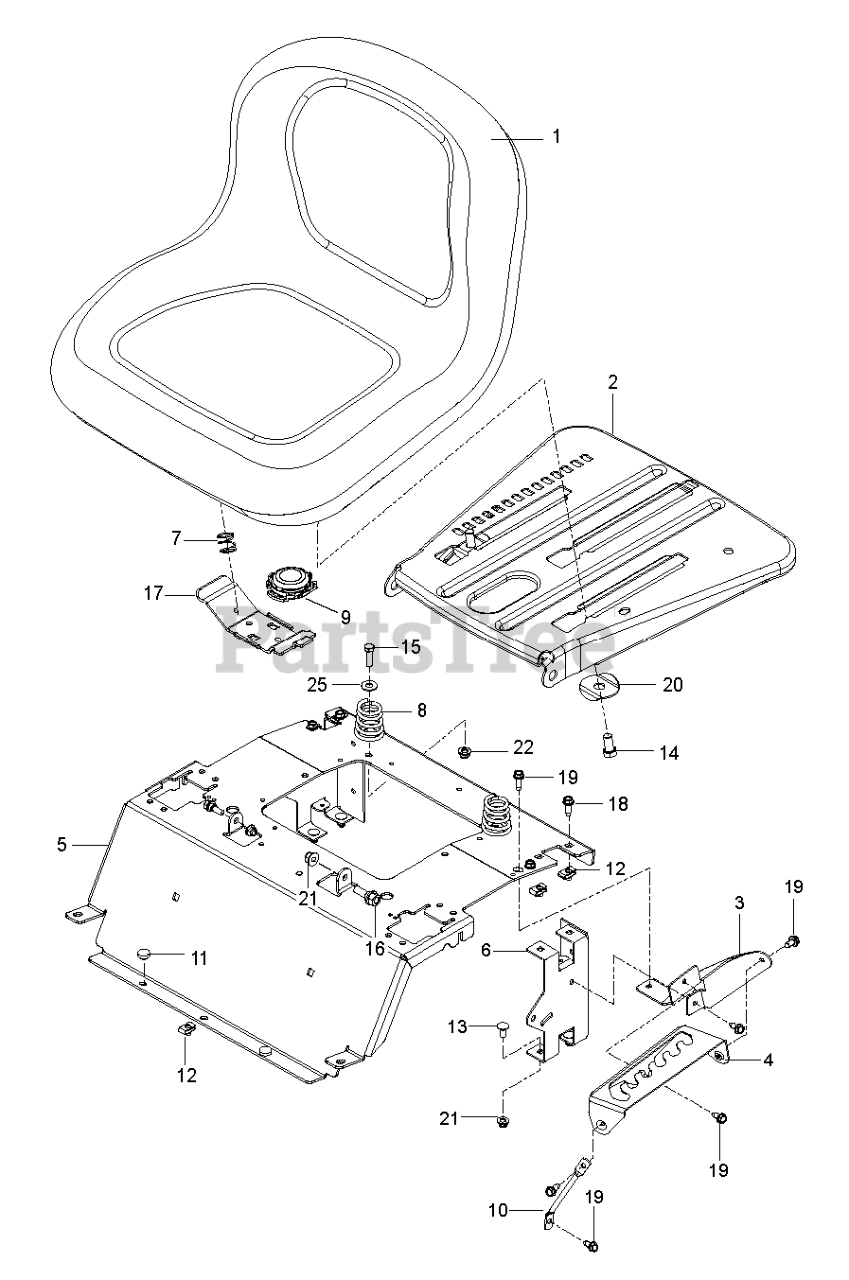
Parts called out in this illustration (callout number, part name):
1	SEAT.TH150.MS498.GRY.HUSQ.TEX
2	PLATE.PNT.SEAT.SLIDE.3PT.EDIP
3	PLATE.SUPPORT.DECK.LIFT.X431
4	PLATE.DECK.LIFT.X431
5	PLATE SEAT SUPPORT; RZ ORANGE
5	SUPPORT.SEAT.RZ.HUSQ.ORANGE
6	SUPPORT REAR SEAT BLACK
7	SPRING.LATCH.SEAT.TEX
8	SPRING.COMPRESS.SEAT.TAPERED
9	SWITCH.SEAT.DELTA.OPC.
10	SUPPORT.LEG.DECK.LIFT
11	GROMMET.BUMPER
12	U-CLIP 5/16-18 NUT RETAINER
13	BOLT 5/16C X 3/4" CARRIAGE
14	BOLT
14	RHSNB 5/16-18 X 2-1/2 GR5 ZD
15	BOLT
16	BOLT, SHOULDER
17	HANDLE.SLIDE.SEAT.TEX.BLACK
18	SCREW.THDROL.5/16-18X3/4.TTY
19	BOLT.5/16HEX.WHS.HD
20	WASHER.WINGED.3/8ID.1.5OD
21	5/16-18 NYLOC FLANGE NUT
22	NUT 3/8-16 HEX FLG NYLOC ZD
25	RP WASHER 3/8 FLAT
